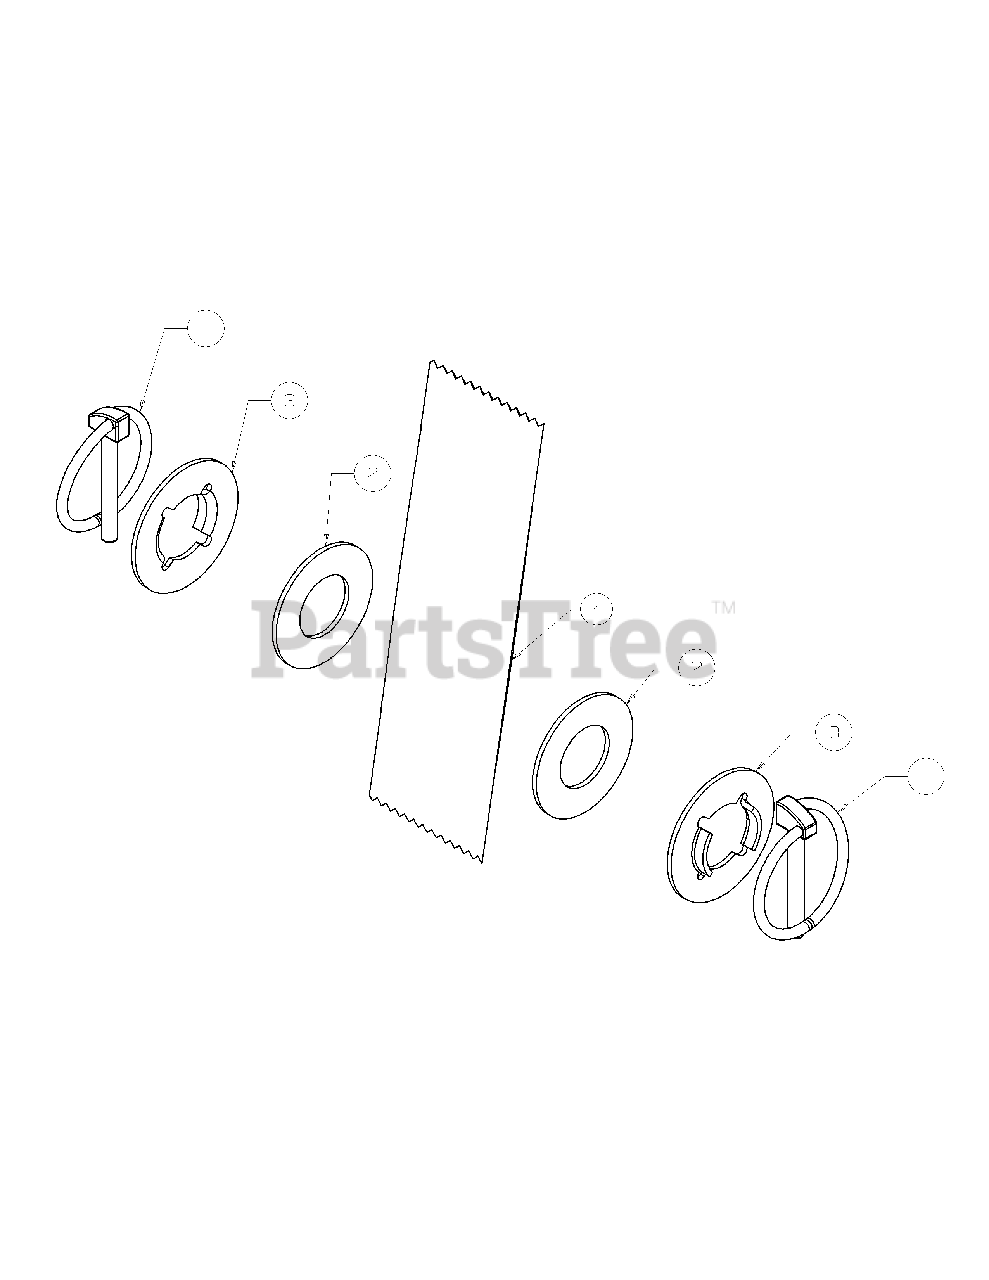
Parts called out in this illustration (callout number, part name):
1	Pin-Lynch
2	Washer-Fl-.760Id X
3	Washer-Flat .781 I
4	Grease
